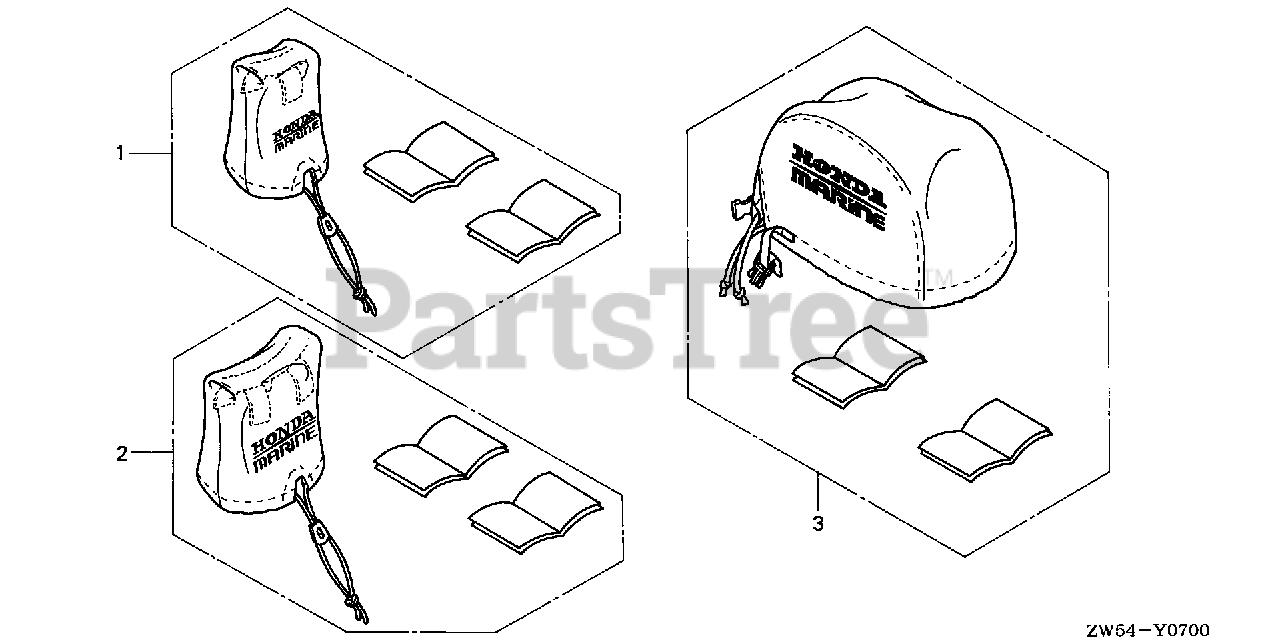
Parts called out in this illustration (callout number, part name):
1	COVER KIT, REMOTE CONTROL BOX
2	COVER KIT, REMOTE CONTROL BOX
3	COVER KIT, ENGINE (BF115/130)
